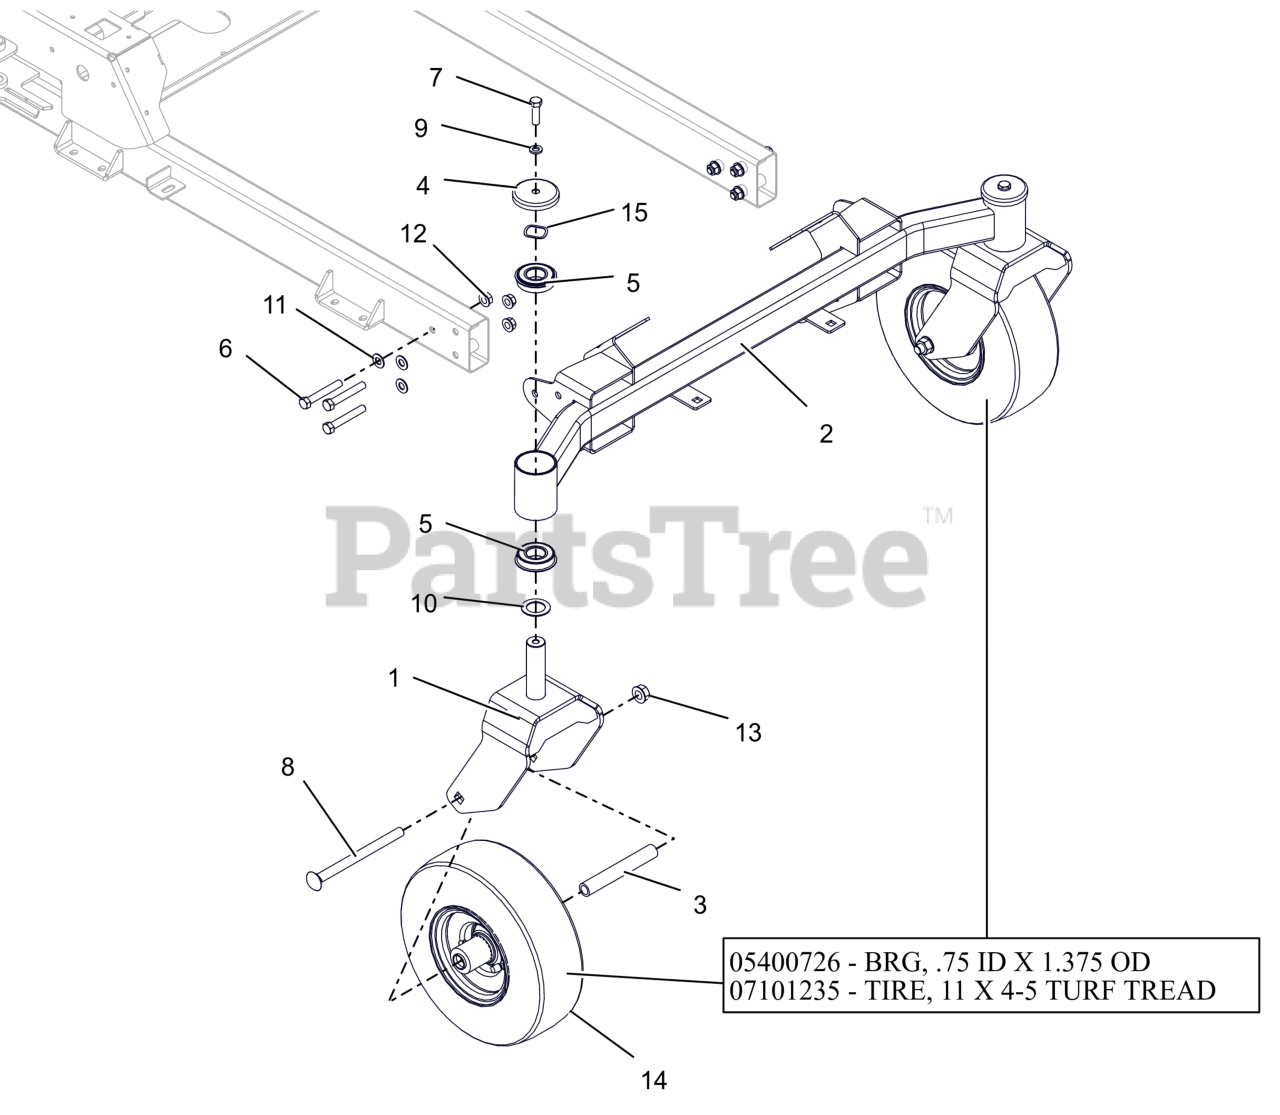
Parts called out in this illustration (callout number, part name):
1	WLDMT, CASTER FORK-X (RED)
2	WLDMT, FRONT AXLE-X/XL (RED)
3	SPACER, ROLLED WHEEL
4	SHIELD, AXLE BEARING
5	BEARING, BALL -2.000 OD X 1.000 ID X .5625 W/RING
6	BLT, HEX .38-16X2.50 G8 ZCC
7	BLT, HEX .38-16X1.25 G5 ZCC
8	BLT, RHSN .50-13X6.50 G5 ZCC
9	WSHR,LK-REG .375X.094 ZCC
10	WSHR-HRD-THRS 1.007X1.542X.062
11	WSHR-FL-STL 0.406X0.812X0.055 HRD
12	NUT-LK-TOP-FLG .375-16 GG ZCC
13	NUT-LK-TOP-FLG .500-13 GF ZCC
14	ASM, WHL/TIRE 11X4.00-5
14	BRG, .75 ID X 1.375 OD
14	TIRE, 11X4-5 TURF TREAD
15	WSHR-WAVE 1.0X1.25X.028 .145FH
